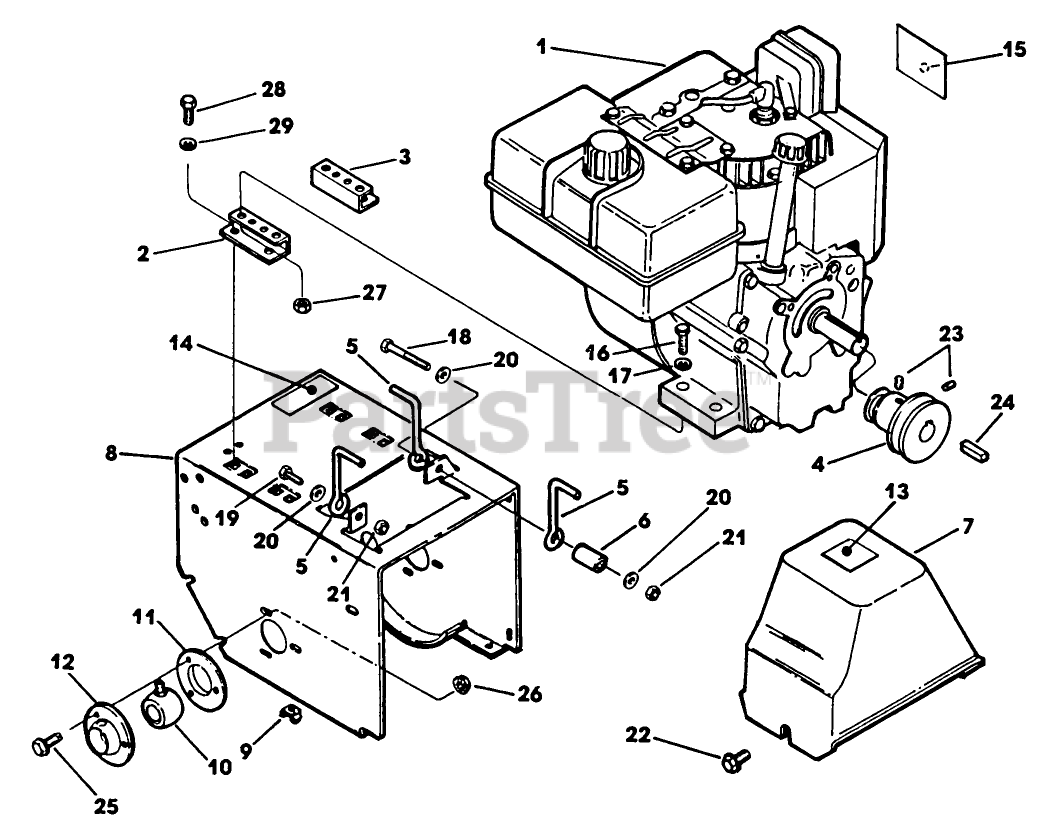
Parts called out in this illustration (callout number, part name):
1	Engine-10 H.P. Tecumseh Snow King w/18W Alt
1	Engine-8 H.P. Tecumseh Snow King w/18W Alt
1	Engine-5 H.P. Tecumseh Snow King
2	ADAPTOR-ENGINE RH
4	PULLEY-CRANKSHAFT
5	GUIDE-BELT
6	SPACER
20	WASHER
21	NUT
23	SET SCREW
27	NUT SS
28	SCREW - HEX
